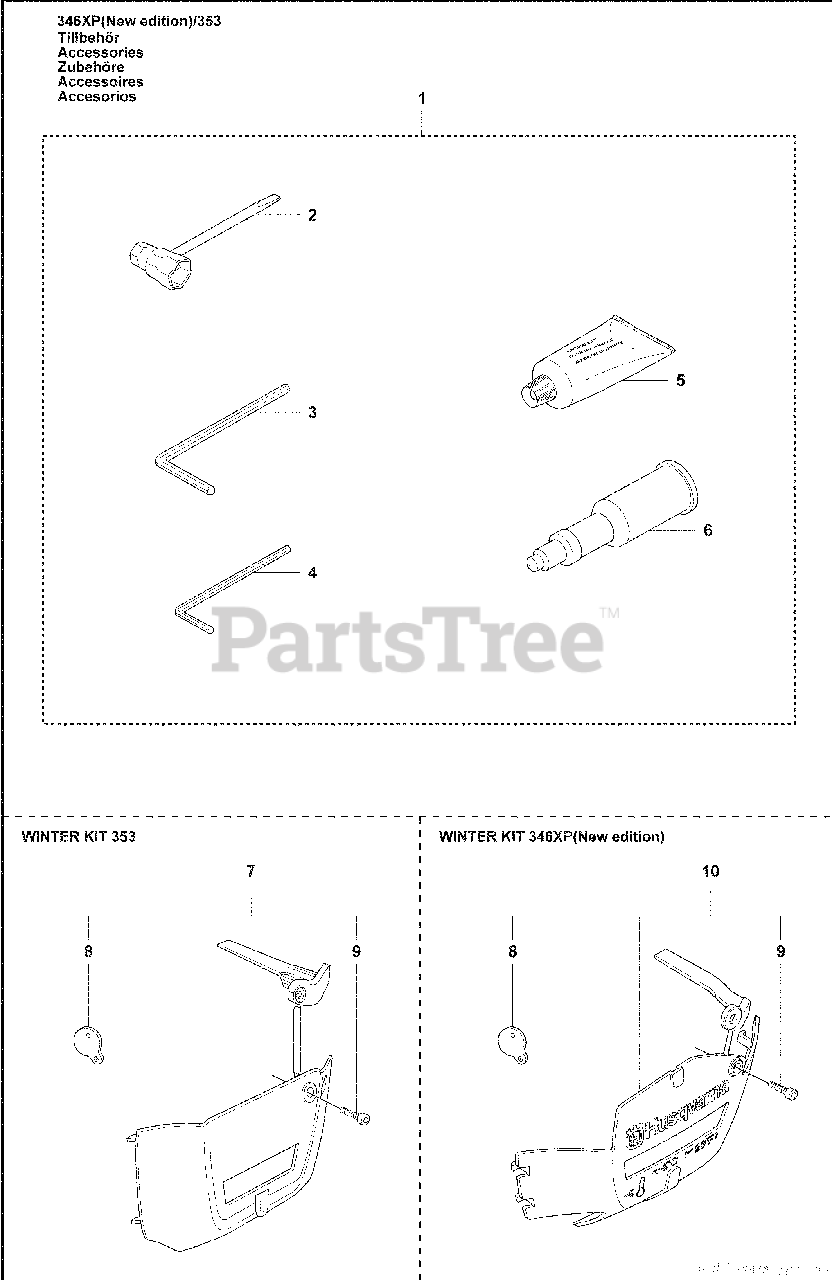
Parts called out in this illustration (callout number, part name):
1	Combi Tool
2	Combi Tool
5	Bearing Grease Tube
6	Grease Gun
7	Winter Cover
8	Plug
10	Winter Cover
